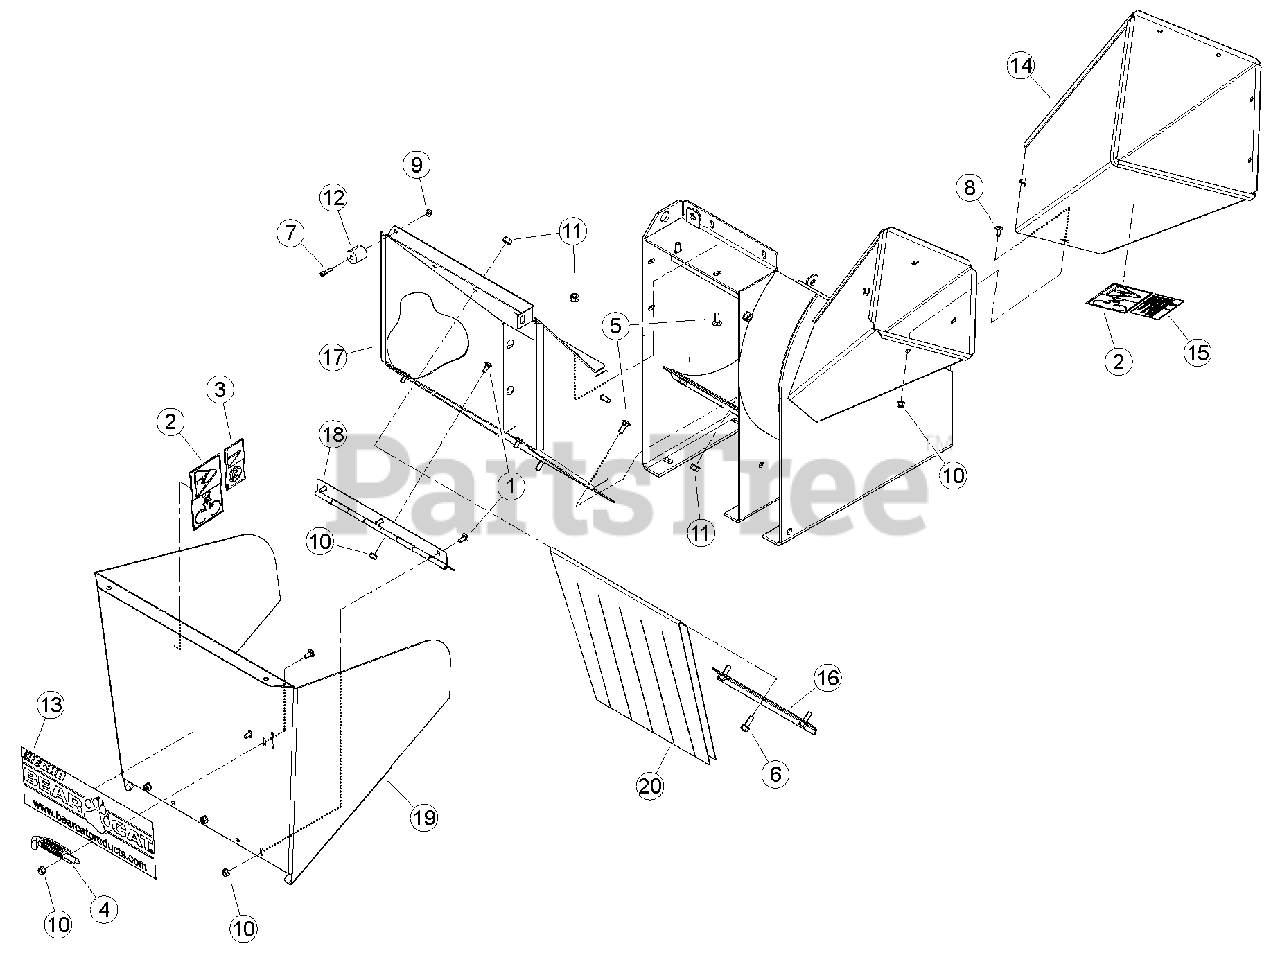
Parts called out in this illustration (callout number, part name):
1	BOLT, 5/16-18 X 3/4 CRG SN GR5
2	DECAL, BLADE DANGER ISO
3	DECAL, SHREDDER SIZE ISO
4	LATCH, RH HINGE
5	BOLT, 3/8-16 X 1 GR5 CRG
6	BOLT, 3/8 X 1 FLANGE NC
7	BOLT, 1/4 X 1 SOC HD CAPSCREW
8	BOLT, 5/16 X 3/4 GR5 CRG NC ZP
9	NUT, 1/4-20 NYLOCK FLANGE
10	NUT, 5/16-18 NYLOCK FLANGE
11	NUT, 3/8-16 NYLOCK FLANGE
12	BUMPER, RECESSED RUBBER
13	DECAL, BEARCAT WEB
14	ASSEMBLY, COMM CHUTE EXTENSION W/ DECAL
15	DECAL, MULTILINGUAL MANUAL
16	ANGLE, FLAP ANCHOR
17	WELDMENT, CHUTE
18	HINGE, EXTENSION TRAY
19	TRAY, CHUTE EXTENSION
20	FLAP, C/S/B CHUTE
